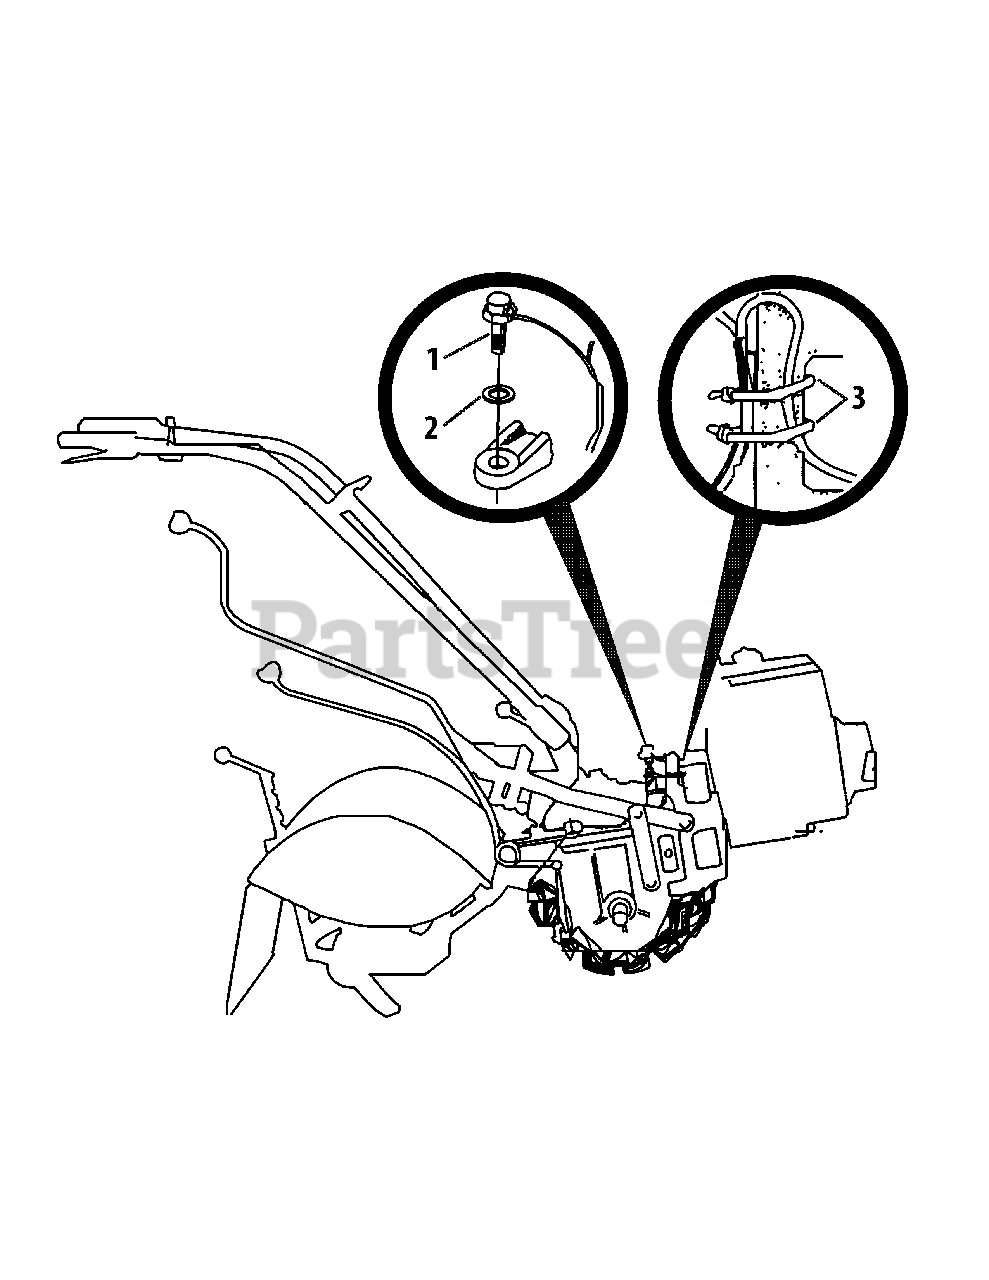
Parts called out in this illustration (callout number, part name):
1	Forward Engine Wire Harness Ass.
2	Internal L-Washer, 9/16"
3	Plastic Tie
